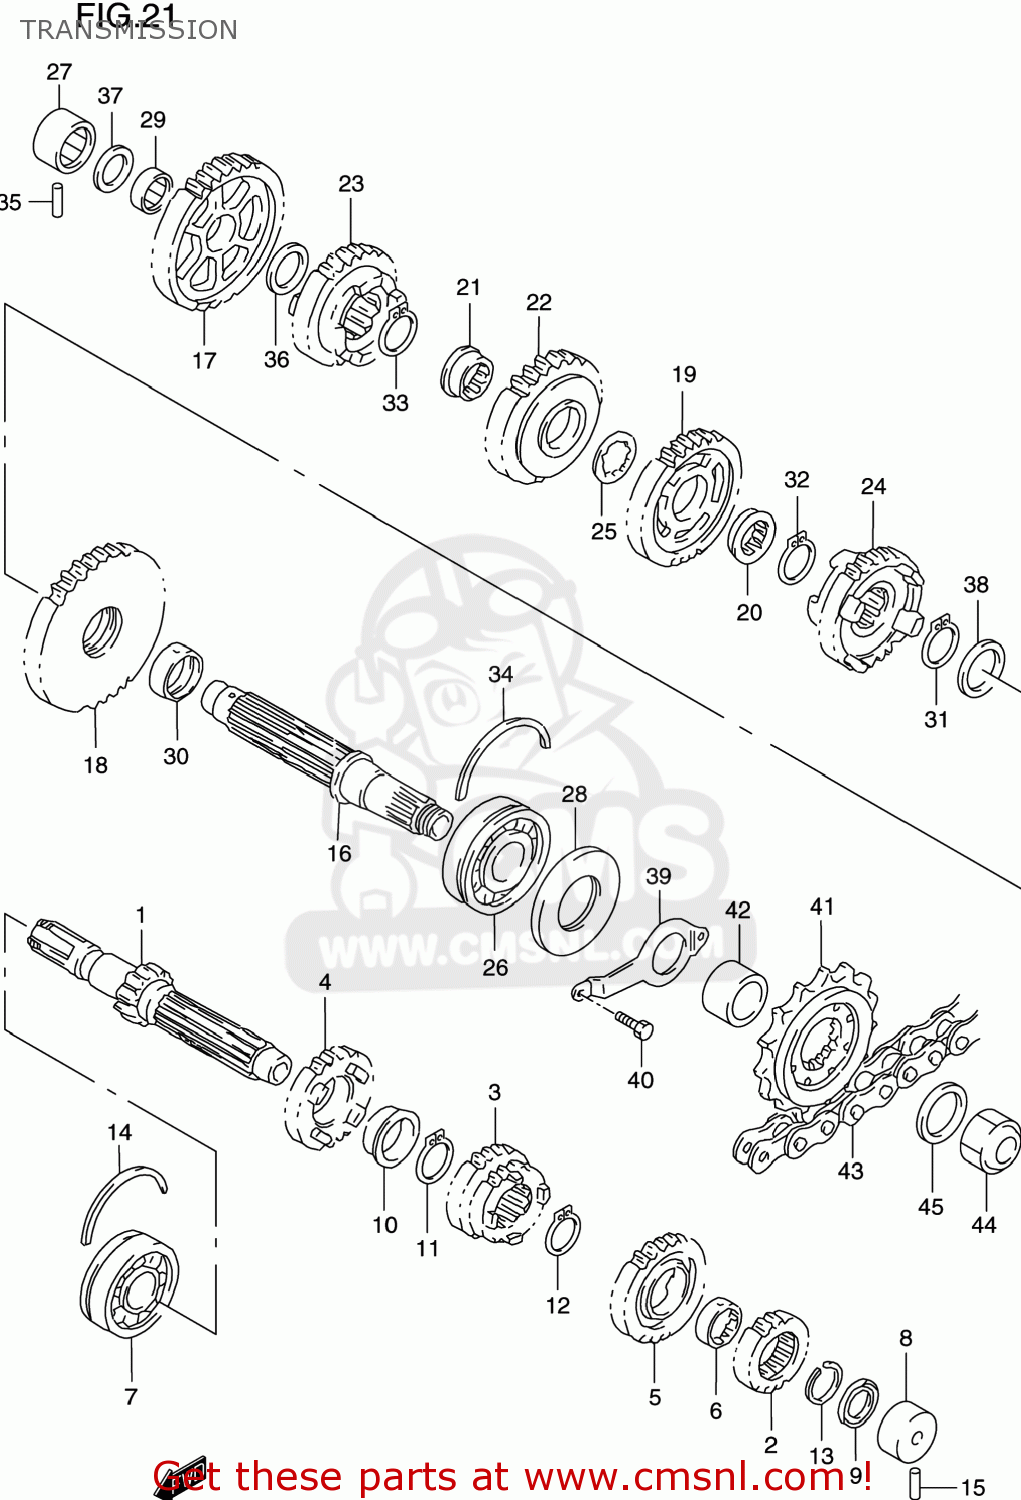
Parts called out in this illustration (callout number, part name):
1	SHAFT,COUNTER
2	GEAR,2ND DRIVE
3	GEAR,3RD & 4TH DRIVE
4	GEAR,5TH DRIVE
5	GEAR,6TH DRIVE
6	BUSH,6TH DRIVE GEAR
7	BEARING(25X62X17)
8	BEARING
9	SEAL,OIL(20X31.2X2.7)
10	BUSH(28X32X2)
11	CIRCLIP
12	CIRCLIP
13	CIRCLIP
14	C RING
15	PIN
16	SHAFT,DRIVE
17	GEAR,1ST DRIVEN
18	GEAR,2ND DRIVEN
19	GEAR,3RD DRIVEN
20	BUSH
21	BUSH
22	GEAR,4TH DRIVEN
23	GEAR,5TH DRIVEN
24	GEAR,6TH DRIVEN
25	WASHER,LOCK
26	BEARING(28X70X18)
27	BEARING(20X34X20)
28	SEAL,OIL(34.8X70X6)
29	BUSH(22X26X9)
30	BUSH(28X32X9.5)
31	CIRCLIP
32	CIRCLIP
33	CIRCLIP
34	C RING
35	PIN
36	SHIM(20X34X1)
37	SHIM(22X34X1)
38	SHIM(28X38X1)
39	RETAINER,CL PUSH ROD OIL SEAL
40	BOLT
41	SPROCKET,ENGINE(16T)
42	SPACER,ENG SPROCKET
43	CHAIN,DRIVE(DID525V9,108L)
44	NUT
45	WASHER(25X41X3)
